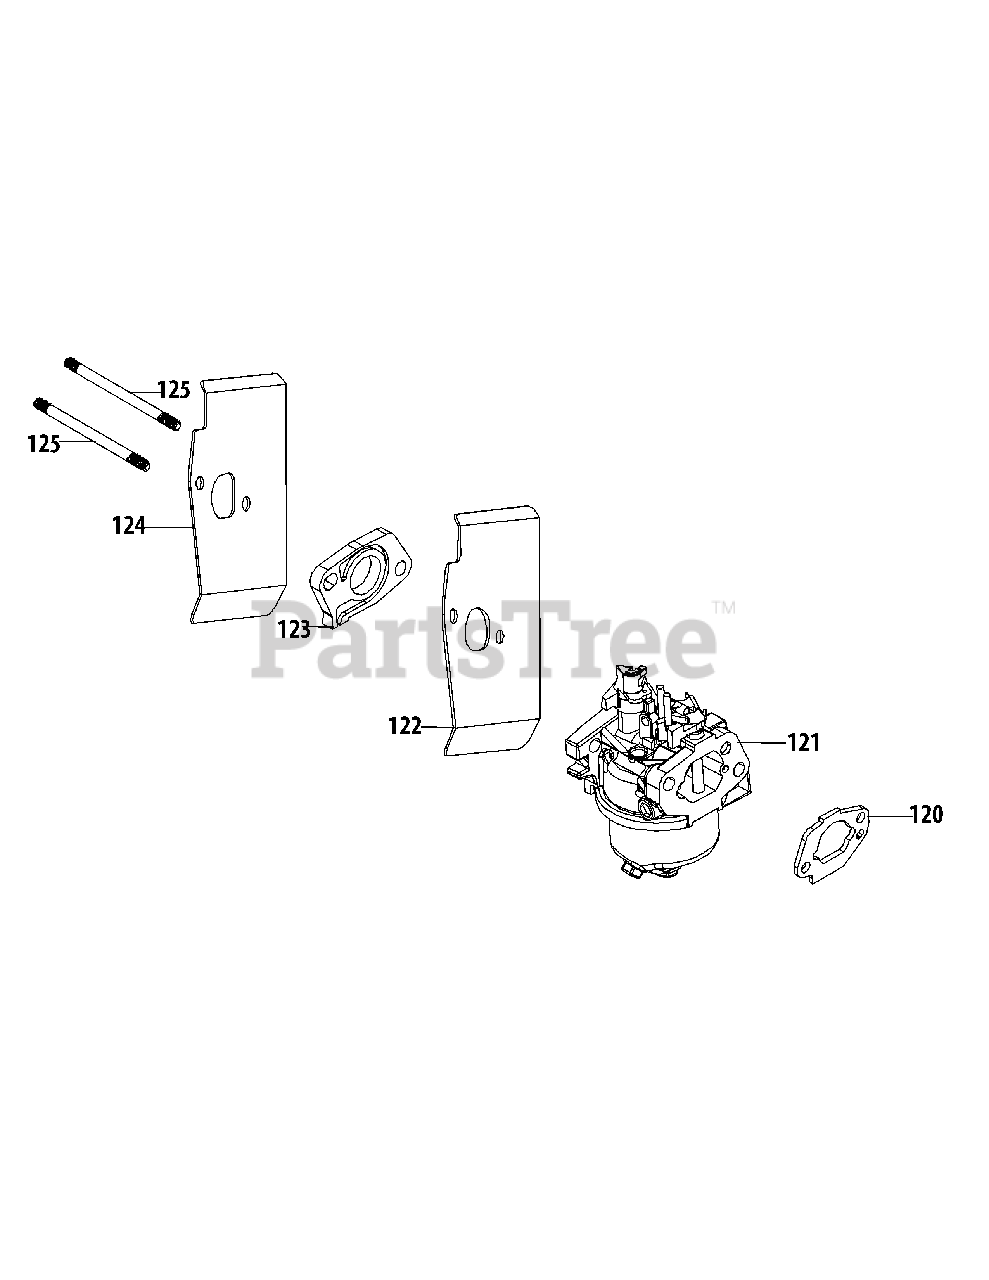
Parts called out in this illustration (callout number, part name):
120	Air Filter Base Gasket
121	Carburetor Assembly
121	Carburetor Rebuild Kit
122	Carburetor Gasket
123	Carburetor Insulator
124	Carburetor Gasket
125	Carb Stud M6×87
